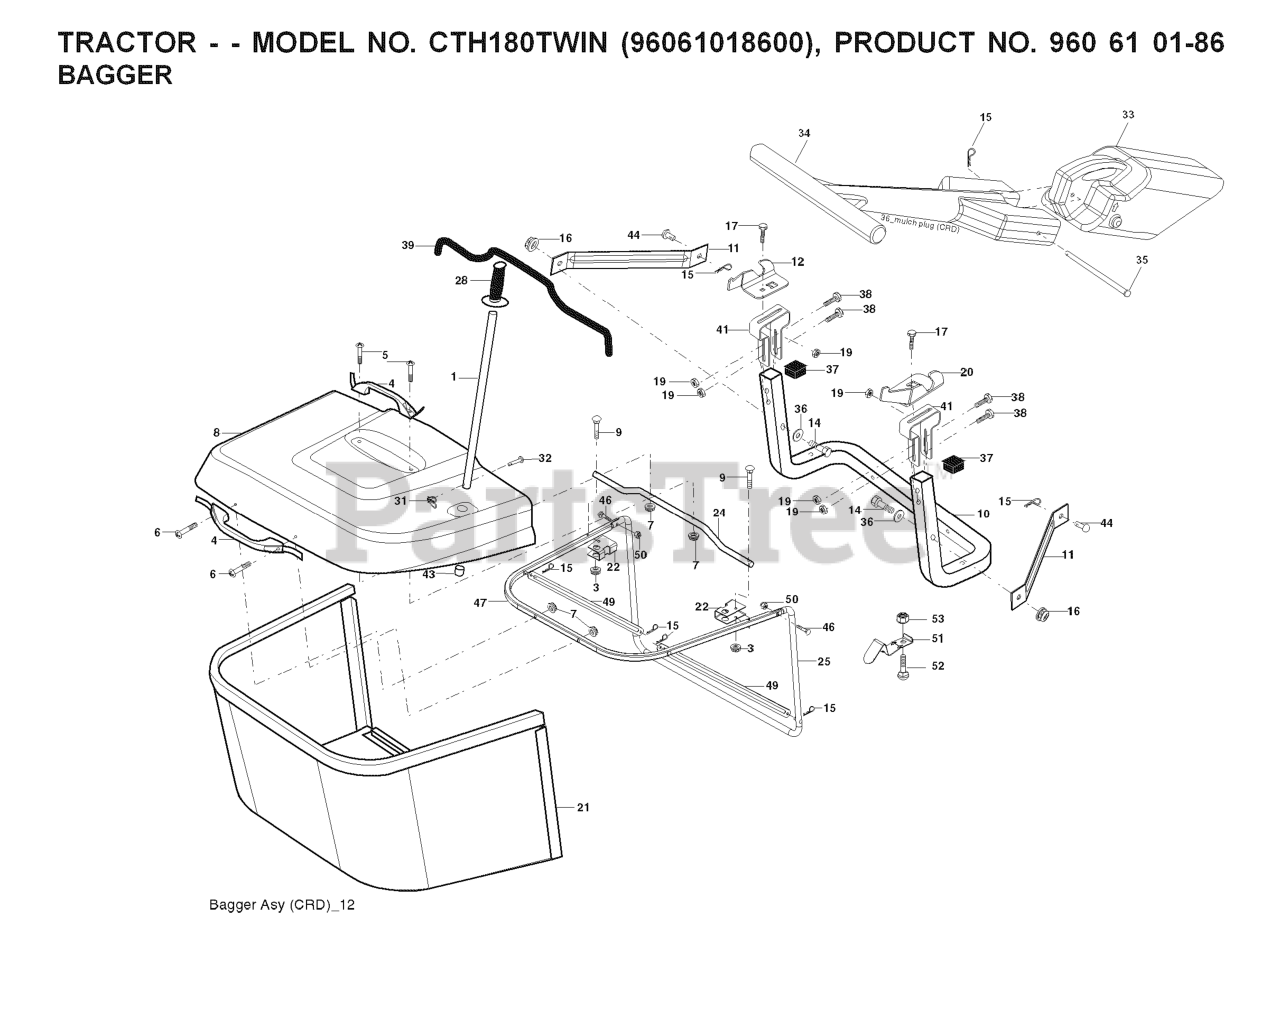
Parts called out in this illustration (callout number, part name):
1	TUBE HANDLE
3	NUT T
4	HANDLE.BAGGER.W/LVRS.BLK.CRD
5	SCREW.PAN.HEAD
6	REPL BY 532 75 00-29
9	Bolt Carriage 1/4-20 x 2.25d x Gr.5
10	TUBE
11	BRACKET.SUPPORT.UPPER.BAG.CRD
12	BRKT PIVOT
14	BOLT-HEX EAK
15	RETAINER-SPRNG RB
16	NUT LOCK FLG 3/8-16 UNC
17	RP BOLT 5/16-18 X3/4 ZN/YEL GR
19	NUT LOCK HEX FLANGE 5/16-18
20	BRKT.PIVOT.RH.CRD
21	BAGGER.ASM.CRD.2007
22	BRKT.SIDE.BAG.CRD
24	TUBE.PIVOT.BAG.CRD.BLACK
25	PIPE
28	GRIP.HANDLE.BLACK
31	RETAINER CLIP
32	RIVET,DRILLED
33	MULCH PLUG, CTH150
34	HANDLE.MULCHER.92.CRD (2 2)
36	WASHER
37	Plug Support Bagger CRD
38	BOLT.5/16-18X2.5
39	SEAL.TRIM.37'
41	BRKT.VERT.ADJ.BAGGER.CRD
43	PLUG, TUBING END
46	BOLT.CARRIAGE.5/16-18
47	PIPE
49	ROD
50	NUT.71038.31-18.HEX.NYLOCK
51	LATCH
52	BOLT
53	NUT
